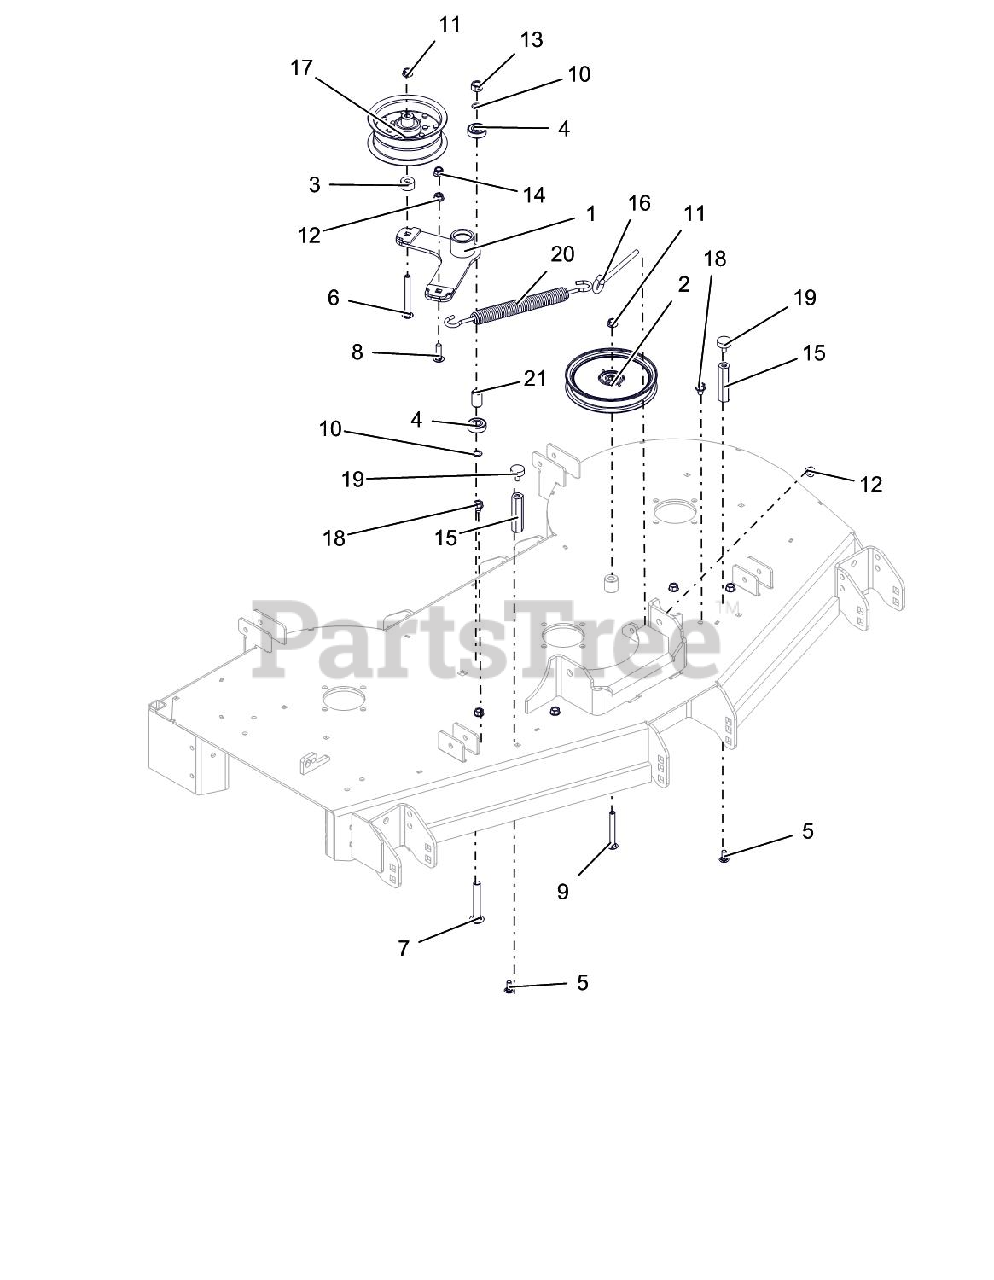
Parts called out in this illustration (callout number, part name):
1	WLDMT, IDLER ARM
2	IDLER, FLAT - 6.00" X .75"
3	SPACER .390X1.000X.562
4	BRG-BALL .500X1.375X.44
5	BLT, RDHDSQNK .31-18X.75 LOCTITE
6	BLT-RHDSSQNK .38-16X3.50 G5YZ
7	BLT-RDHDSQSHNK .50-13X3.25 YWZC
8	BLT-RHDSSQNK .38-16X1.25 G5YZ
9	BLT-RDHDSQNK .38-16X3.00 G5 YWZC
10	WASHER-FLAT-STL, .500 X .750 X .020
11	NUT, LK-CTR-FLG .38-16 YWZC
12	@NUT-SPNLK-FLG .375-16 YWZC
13	NUT-LK-CTR .50-13 YWZC
14	NUT-LK-NYL-FLG .38-16 YWZC
15	NUT, COUPLING .31-18 X 3.00
16	BOLT, EYE .38-16X6.00 .62 DIA
17	PULLEY, FLAT 5.00X2.36X.375
18	SCR-TAP .38-16X.50 HWH TR YWZ
19	BUMPER, RUBBER
20	SPRG, EXTENSION - SWIVEL
21	SPACER, .510 X .750 X 1.148
